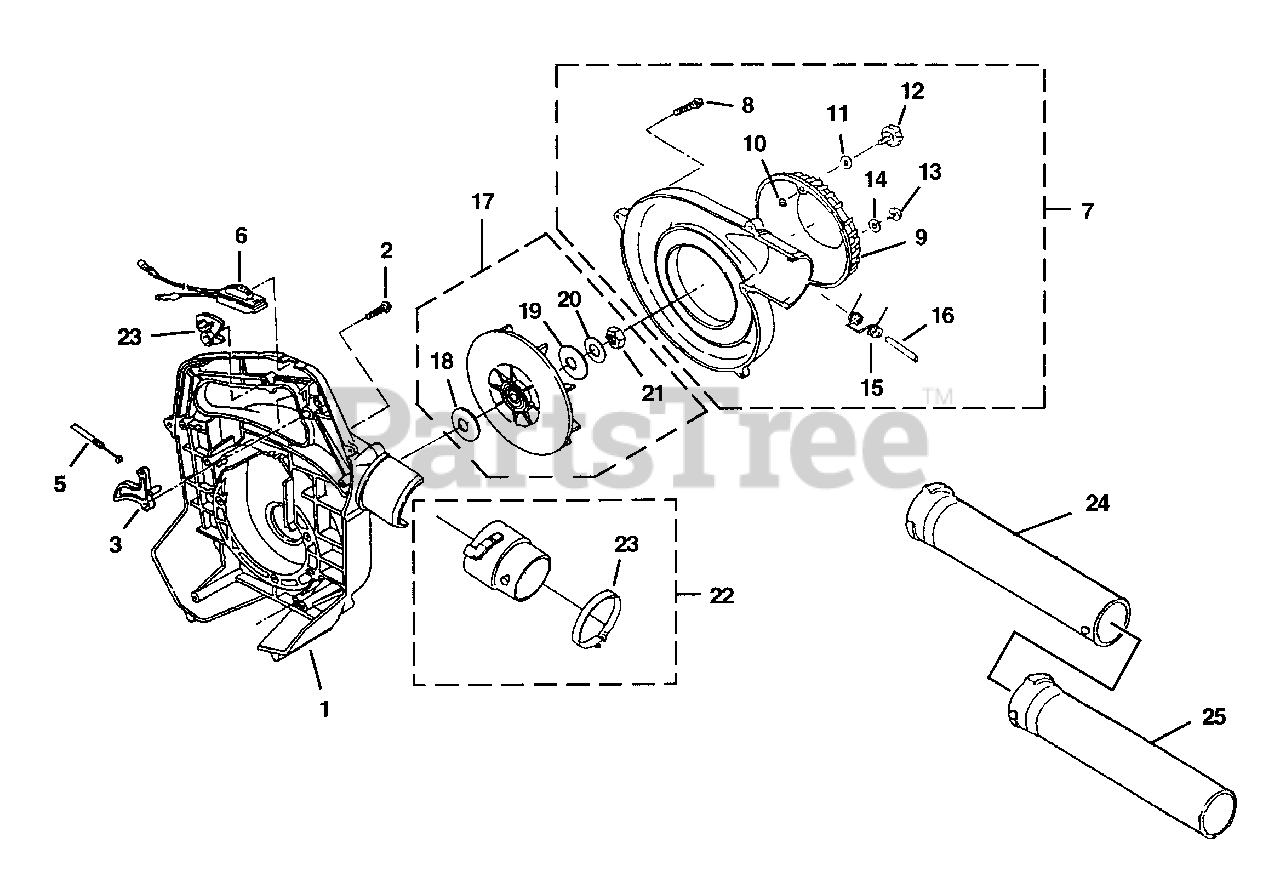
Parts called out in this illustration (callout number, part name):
1	VOLUTE (Inner)
2	SCREW ASSEMBLY (M5 x 35 W SW)
3	TRIGGER-Throttle
4	LOCK- Throttle
5	CABLE-Throttle
7	VOLUTE COMPLETE (Outer)
8	SCREW-Tapping (M5 x 20)
10	SNAP RING-Outer
13	SCREW-Tapping (M5 x 14)
14	WASHER (M5)
16	SHAFT-Hinge
17	FAN ASSEMBLY
19	WASHER (M8)
20	WASHER (M8)
21	NUT (M8 x 6)
22	TUBE ADAPTER & CLAMP
24	TUBE-Rear
25	TUBE-Front
